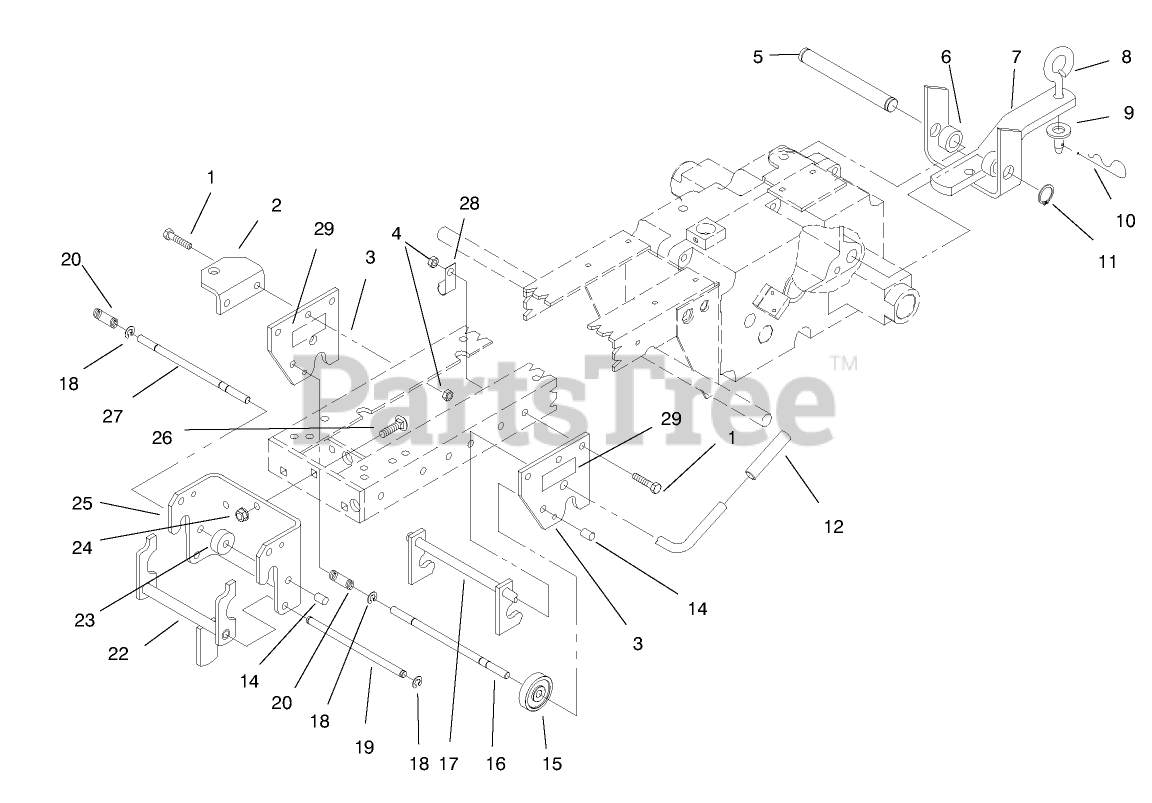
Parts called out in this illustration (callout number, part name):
1	SCREW-HH
2	SUPPORT
3	PLATE-HITCH
4	NUT-HEX
5	PIN-STATIONARY HITCH
6	SPACER
8	PIN-TOOL
9	WASHER-FLAT
10	PIN-HAIR
11	E-RING
12	GRIP
14	CAP-ROD, PLUNGER
16	ROD-LOCK
17	MID HITCH ASM
18	RING-RETAINING
19	ROD-LATCH PIVOT
20	SPRING
22	LATCH
24	NUT-LOCK, NI
25	HITCH-FRONT
26	BOLT-CARR
27	ROD-LOCK
28	CLIP
29	DECAL-ATTACH A-MATIC
